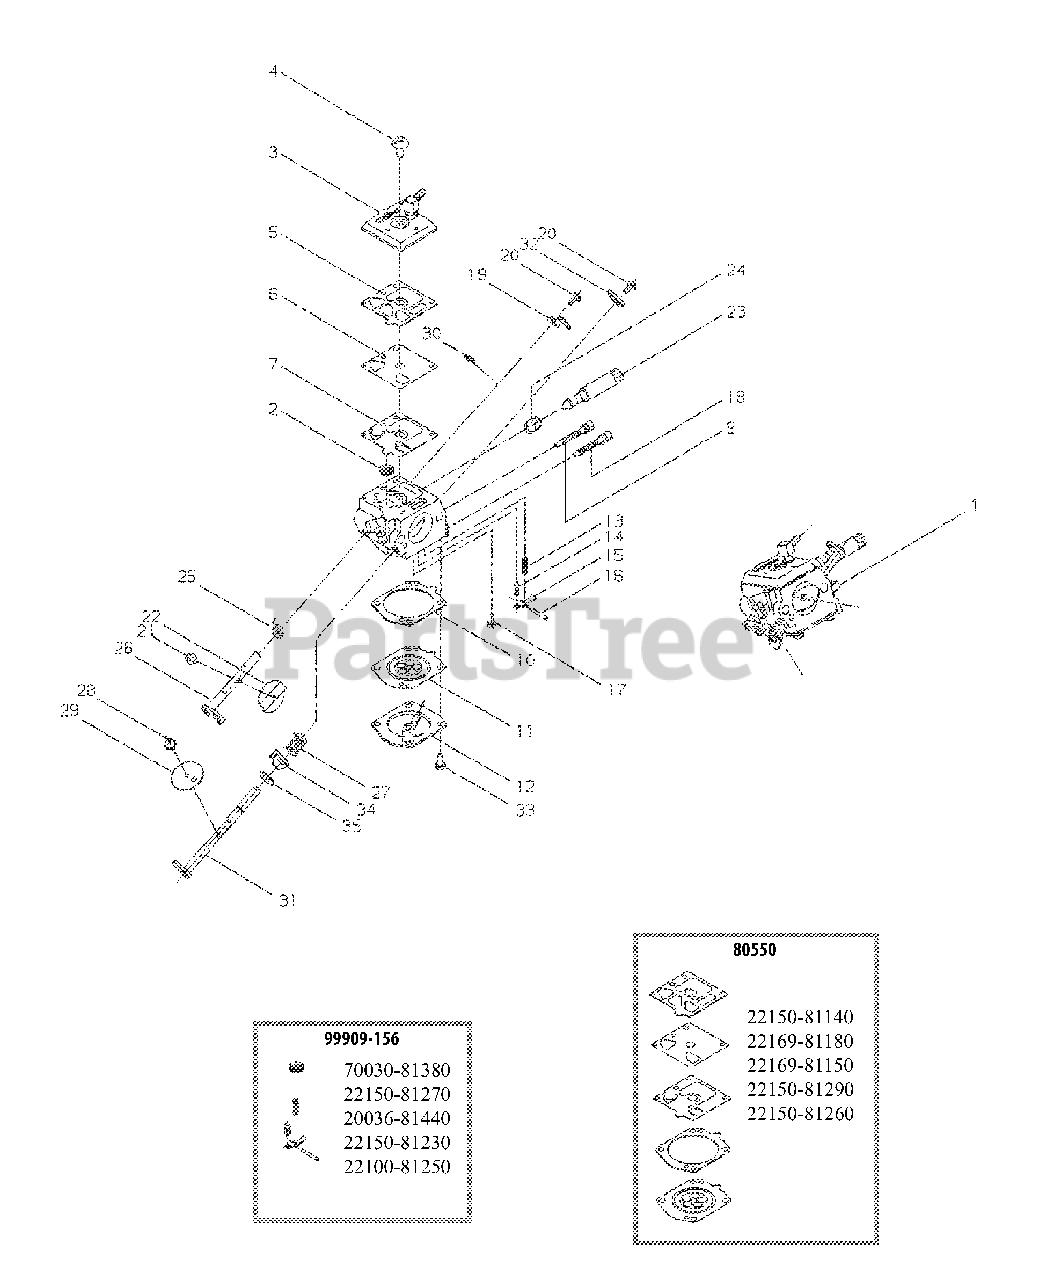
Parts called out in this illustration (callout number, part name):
1	CARBURETOR
2	STRAINER
3	COVER, PUMP
4	SCREW
5	GASKET, PUMP
6	DIAPHRAGM, PUMP
7	DIAPHRAGM, PUMP
9	NEEDLE - LOW SPEED
10	GASKET, METERING
11	DIAPHRAGM, METERING
12	COVER, DIAPHRAGM
13	SPRING, METERING LEVER
14	VALVE, INLET NEEDLE
15	LEVER, METERING
16	PIN, METERING LEVER
17	SCREW, METERING LEVER PIN
18	NEEDLE - HIGH SPEED
19	STOP, THROTTLE
20	SCREW
21	SCREW
22	VALVE, THROTTLE
23	SCREW, IDLE ADJUST
24	SPRING
25	SPRING, THROTTLE RETURN
26	SHAFT, THROTTLE
27	SPRING, CHOKE RETURN
28	SCREW
29	VALVE, CHOKE
30	RING, RETAINING
31	SHAFT, CHOKE
32	TRIGGER, THROTTLE
33	SCREW
34	LEVER, FAST IDLE
35	WASHER
80550	DIAPHRAGM/GASKET KIT
99909-156	REPAIR KIT
